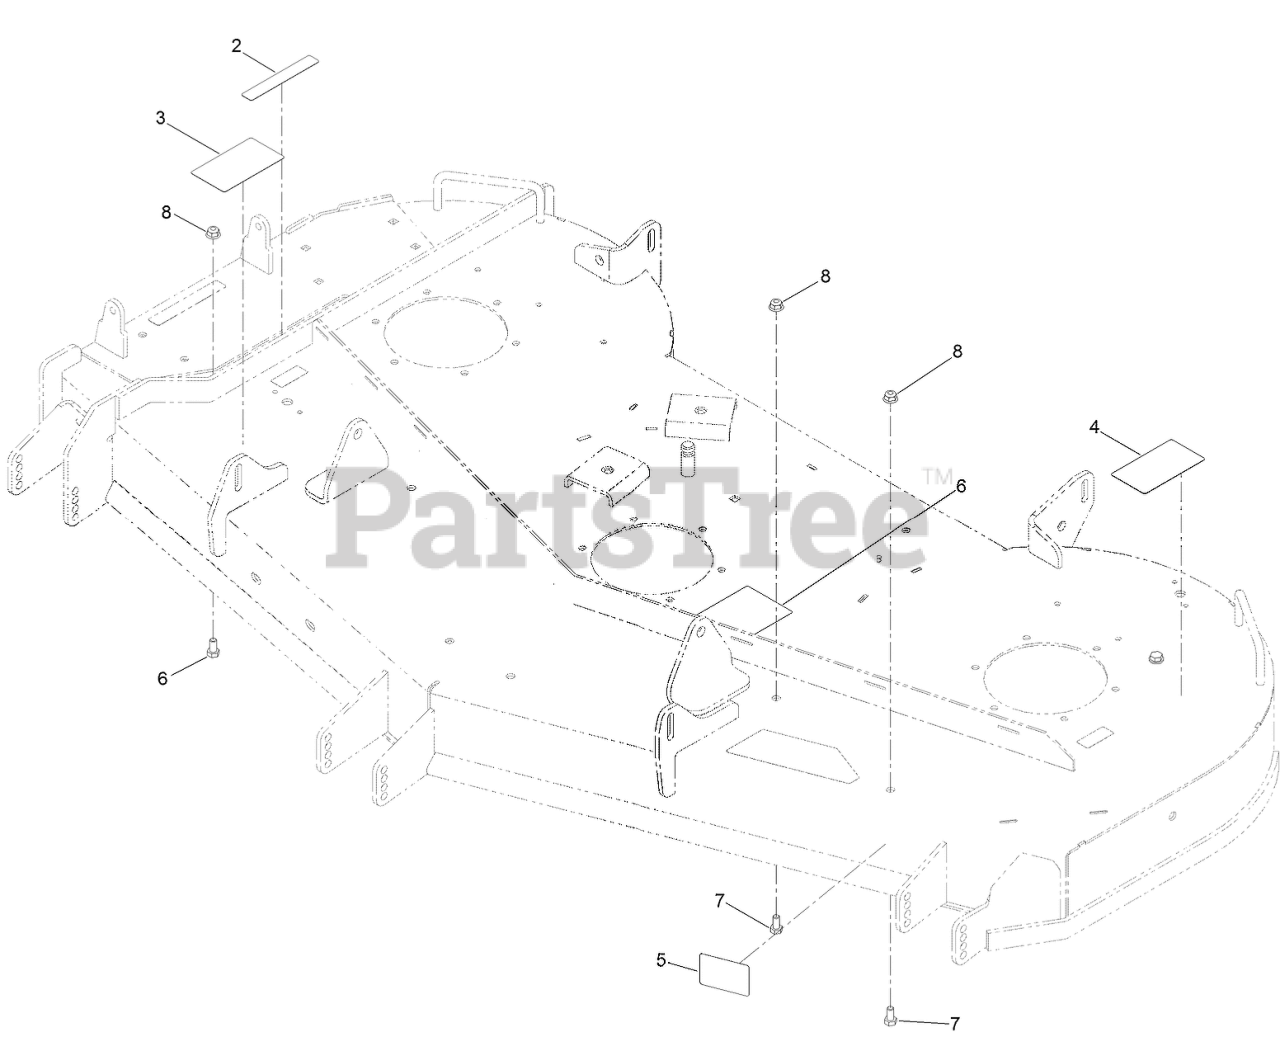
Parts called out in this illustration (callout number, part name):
2	DECAL-DANGER
3	DECAL-DANGER
4	DECAL-DANGER
5	DECAL-SCALP, ANTI
6	DECAL-ROUTING, BELT
7	SCREW-HH
8	NUT-HF, NI
